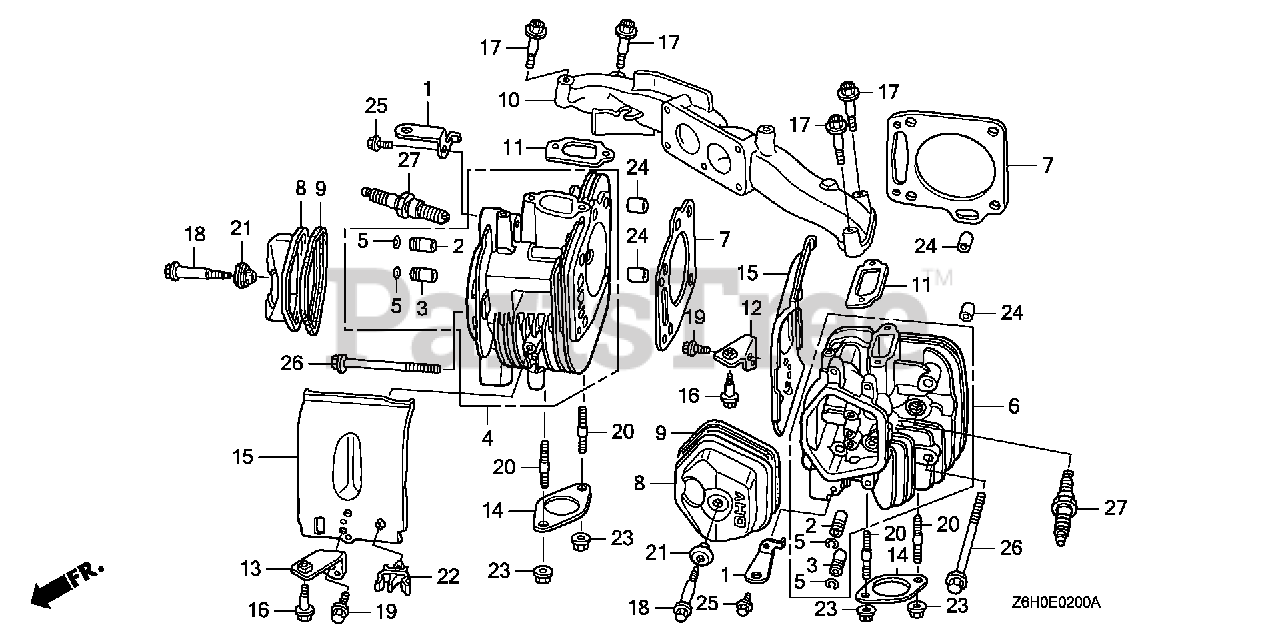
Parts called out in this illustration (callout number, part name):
1	HANGER, ENGINE
2	GUIDE, VALVE (OVER SIZE)
3	GUIDE, EX. VALVE (O.S.)
4	CYLINDER HEAD (#1)
5	CLIP, VALVE GUIDE
6	CYLINDER HEAD (#2)
7	GASKET, CYLINDER HEAD
8	COVER, HEAD
9	GASKET, HEAD COVER
10	MANIFOLD, IN.
11	GASKET, IN. MANIFOLD
12	BRACKET, R. AIR CLEANER
13	BRACKET, L. AIR CLEANER
14	GASKET, EX. PIPE
15	SHROUD, HEAD
16	BOLT, FLANGE (6MM)
17	BOLT, SOCKET (8X45)
18	BOLT, HEAD COVER
19	BOLT, FLANGE (6X14) (CT200)
20	BOLT, STUD (8X22)
21	WASHER, HEAD COVER
22	CLIP, FUEL TUBE
23	NUT, FLANGE (8MM)
24	PIN, DOWEL (12X20)
25	BOLT, FLANGE (8X20)
26	BOLT, FLANGE (10X80)
27	SPARK PLUG (BPR2ES) (NGK)
27	SPARK PLUG (J14CR-U) (DENSO)
27	SPARK PLUG (ZGR4A)
27	SPARK PLUG (J16CR-U) (DENSO)
27	SPARK PLUG (ZGR5A)
